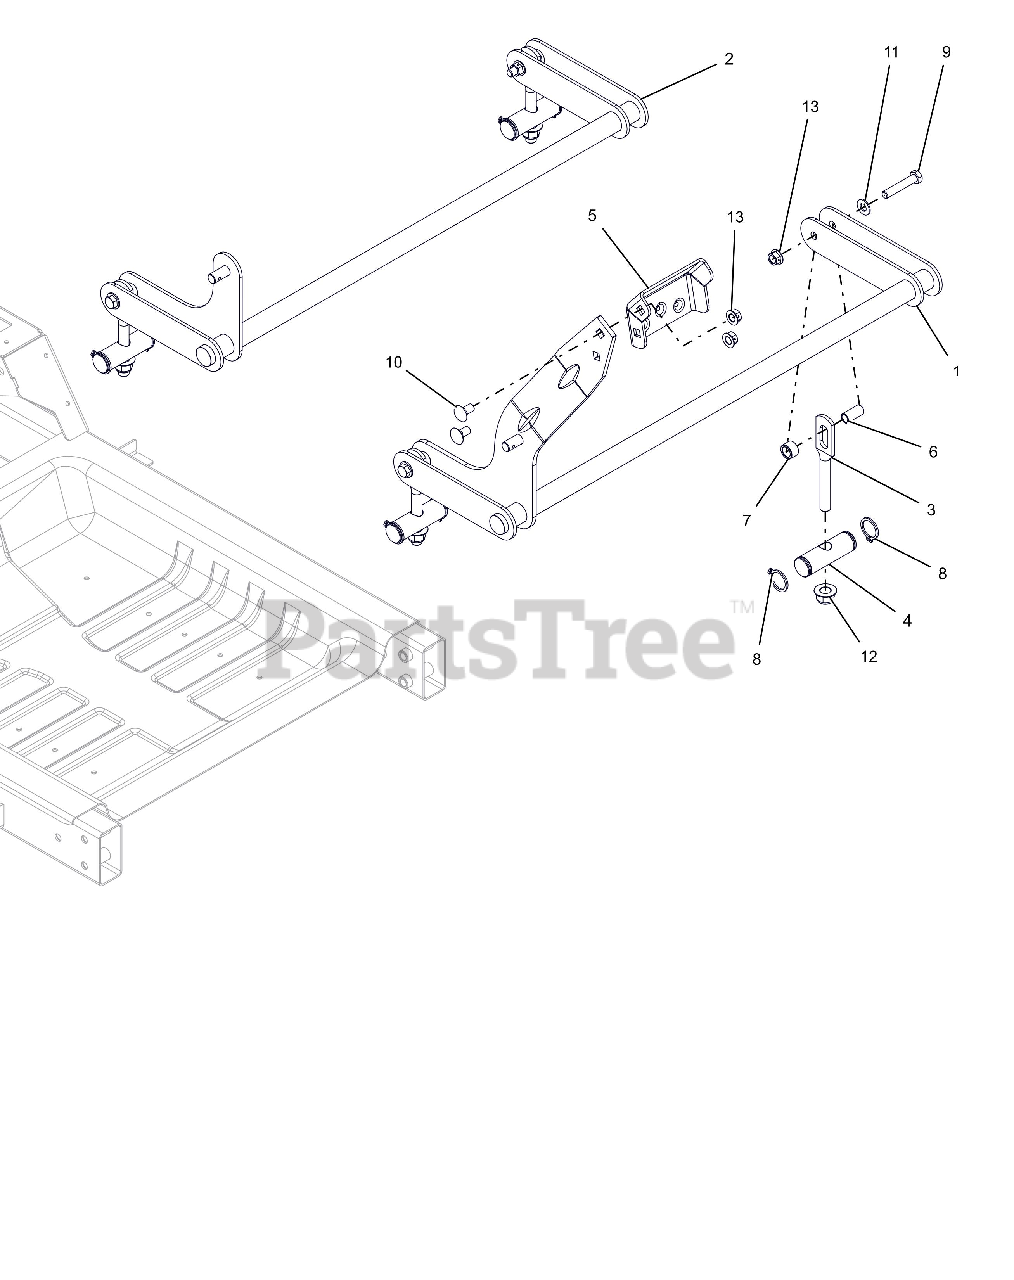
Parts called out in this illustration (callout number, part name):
1	WLDMT, FRONT DECK LIFT PIVOT
2	WLDMT, REAR DECK PIVOT
3	LINK, DECK
4	SHAFT, DECK LINK PIVOT
5	PEDAL, DECK LIFT (BOLT ON)
6	BSHG-SLV .385X.500X1.045
7	BSHG-SLV .510X.751X.475
8	RG-RTNG-EXT 1.00X.078
9	BLT-HEX .38-16X2.00 GR8 YWZC
10	BLT,RHSN .38-16X.75 G5 BFP
11	@WSHR-FL-STL.406X.812X.065 YWZ
12	@NUT-LK-NYL-FLG .50-13 YWZC
13	NUT-LK-CTR-FLG .38-16 YWZC
